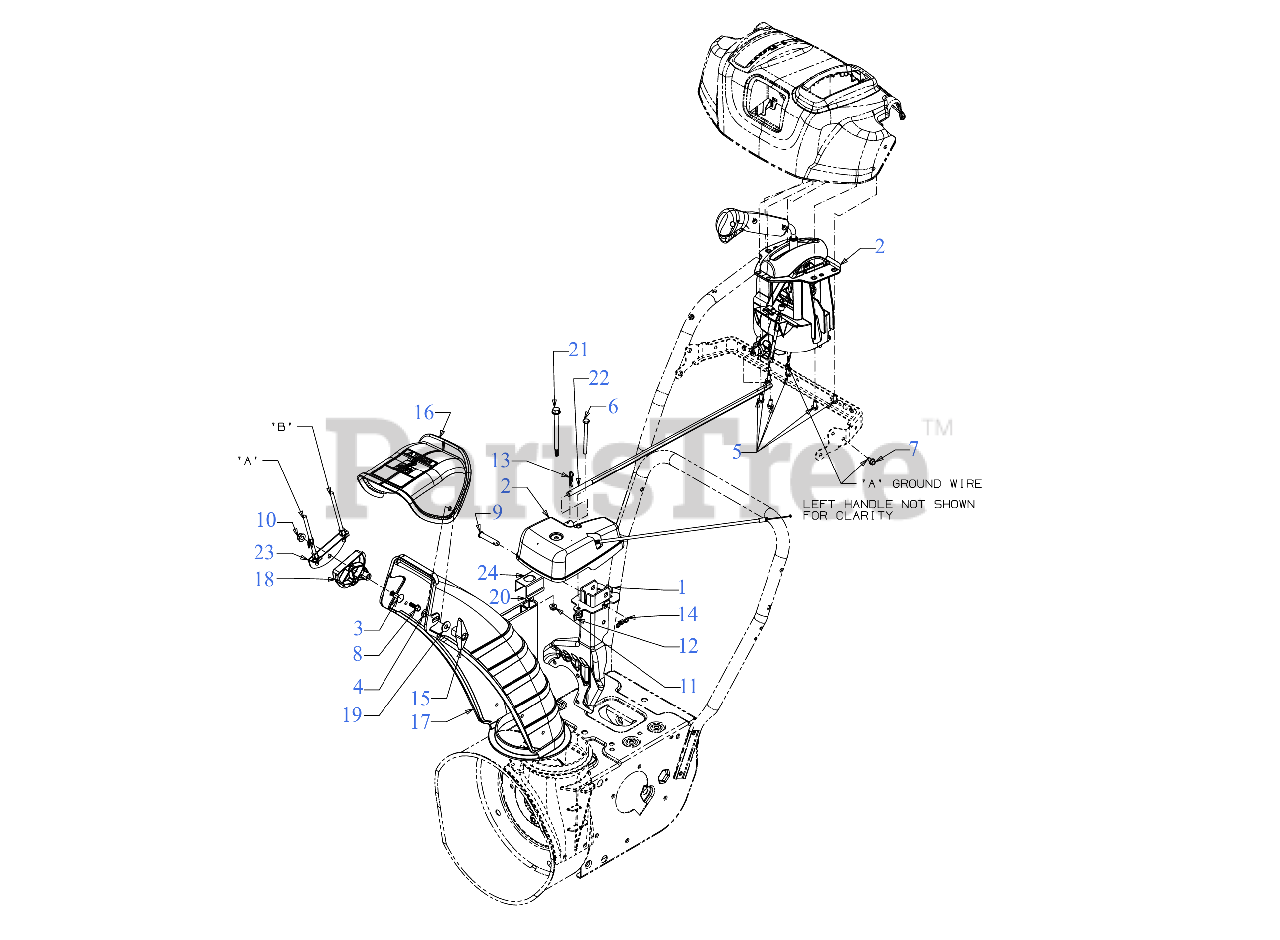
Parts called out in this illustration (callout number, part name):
1	CHUTE SUPPORT BRACKET (POWDER BLACK)
2	CONTROL ASSEMBLY-4-WAY
2	CHUTE GEARBOX ASSEMBLY
3	CARRIAGE BOLT 5/16-18 x 1.50
4	CARRIAGE BOLT 5/16-18 x 1
5	HEX SCREW 1/4-15 x .50
6	SCREW 1/4-20 x 3.0 GR5
7	SCREW 1/4-20 X.500
8	SCREW 1/4-15 x .750
9	CLEVIS PIN 3/8 x 1.87
10	FLANGE LOCK NUT 5/16-18
11	FLANGE LOCK NUT
12	WING NUT 1/4-20
13	INTERNAL COTTER PIN-1/2 DIA
14	BOW TIE COTTER PIN 1/4-5/16
15	WING KNOB NUT
16	UPPER REMOTE CHUTE WITH LABEL
17	LOWER CHUTE 5"
18	CABLE CHUTE GUIDE
19	FLAT WASHER
20	FLAT WASHER
21	SHOULDER SCREW
22	CHUTE ROTATION ROD
23	CABLE BRACKET (POWDER BLACK)
24	CHUTE BRACKET
